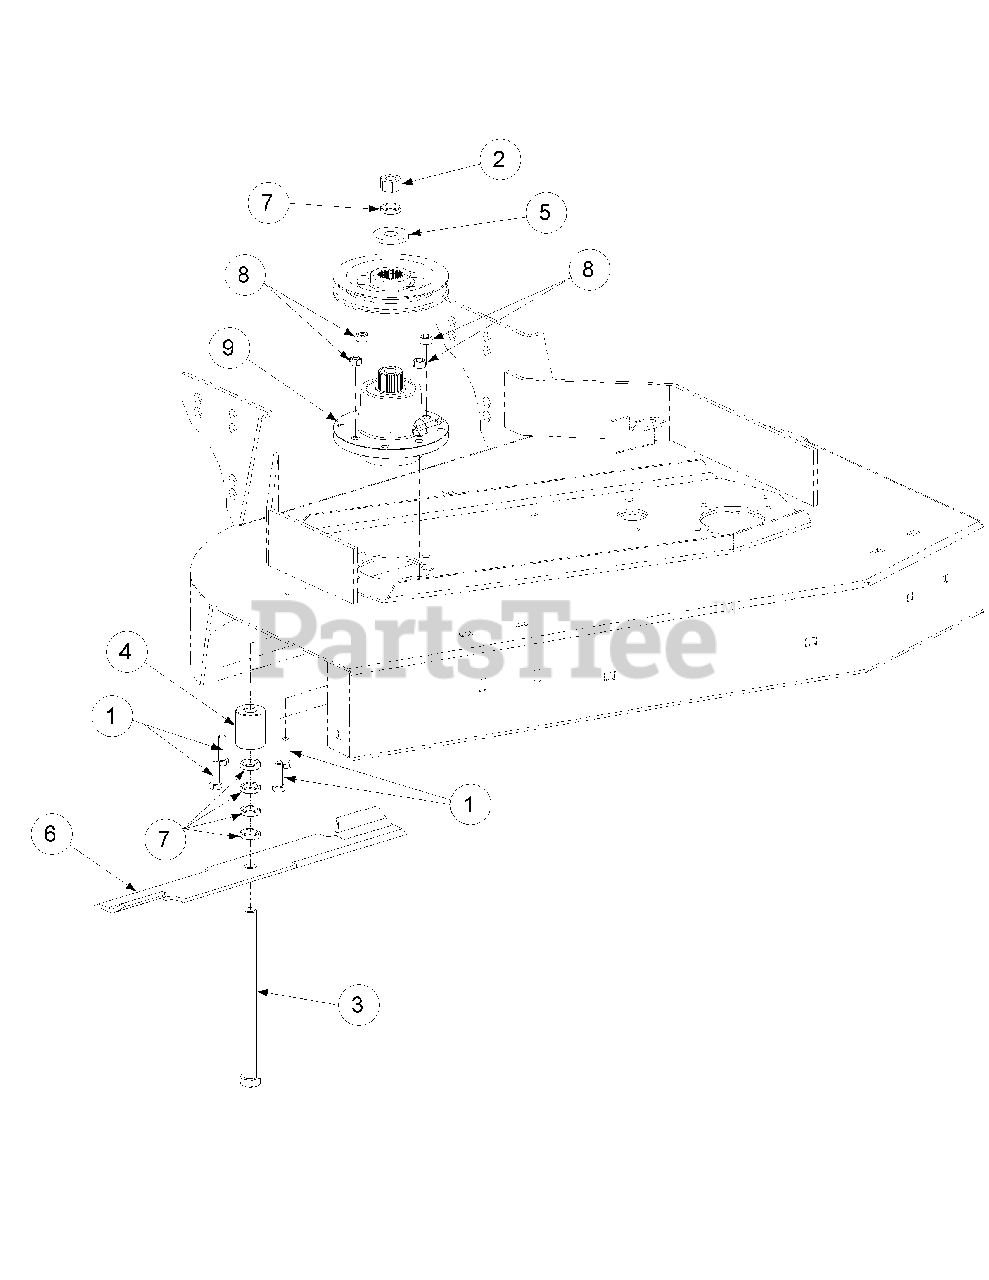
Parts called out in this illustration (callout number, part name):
1	Hex Cap Screw, 3/8-16 x 1-1/4
2	Hex Nut, 5/8-11
3	Hex Cap Screw, 5/8-11 x 9
4	Blade Spacer, .630 x 1.500 x 1.850
5	Flat Washer, .656 ID x 1.313 OD
6	16 1/2" Rotary Blade
7	Blade Spacer, 5/8 ID, 1/4 Thick
8	Hex Nut Flange Lock, 3/8-16
9	Spindle Assembly
